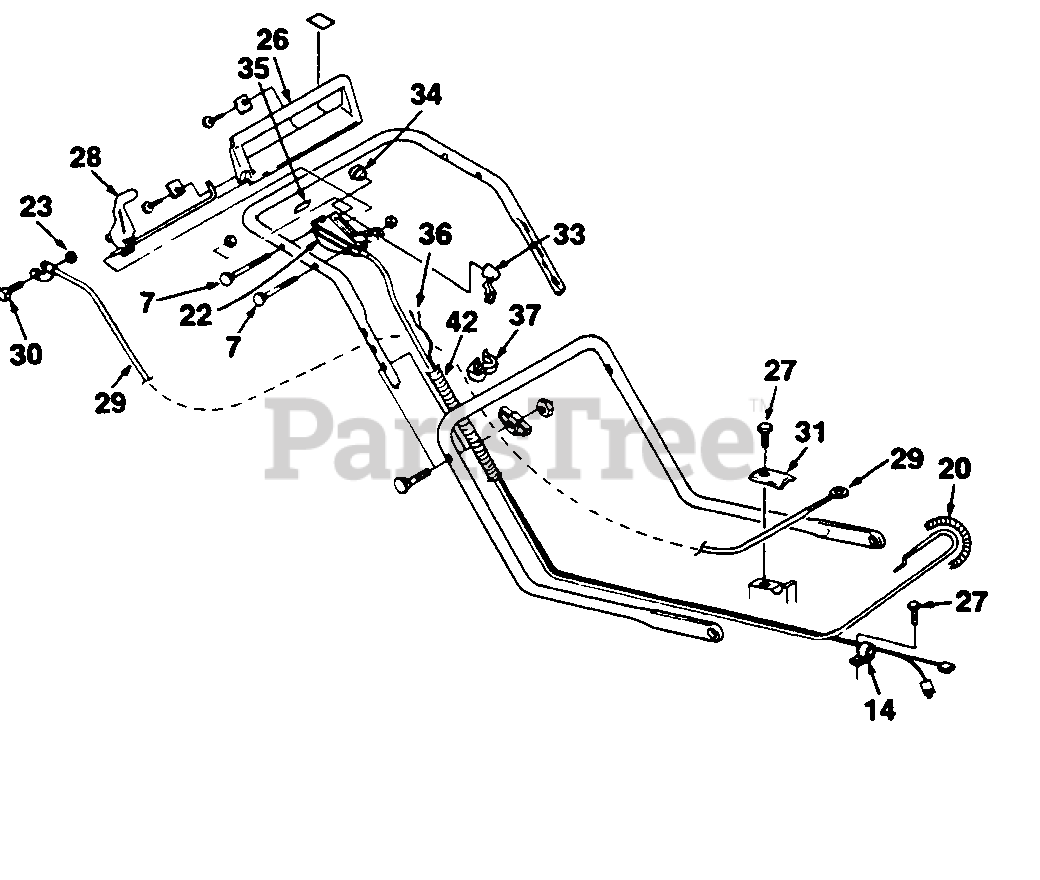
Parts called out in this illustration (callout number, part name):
7	BOLT- Sq. neck
20	COVER - Cable
22	ENGINE - Control
23	NUT-Lock (1/4-20)
26	BAIL- Brake control
27	SCREW- 1/4-20 x 5/8"
28	TRACTION LEVER ASSY.
29	CONTROL CABLE TBO
30	SCREW - 1/4-20 x 1 1/2"
33	HOUSING - Switch
35	Decal - Press to Start
36	HARNESS - Wiring
37	Clip - harness cover
42	COVER - Control cable
